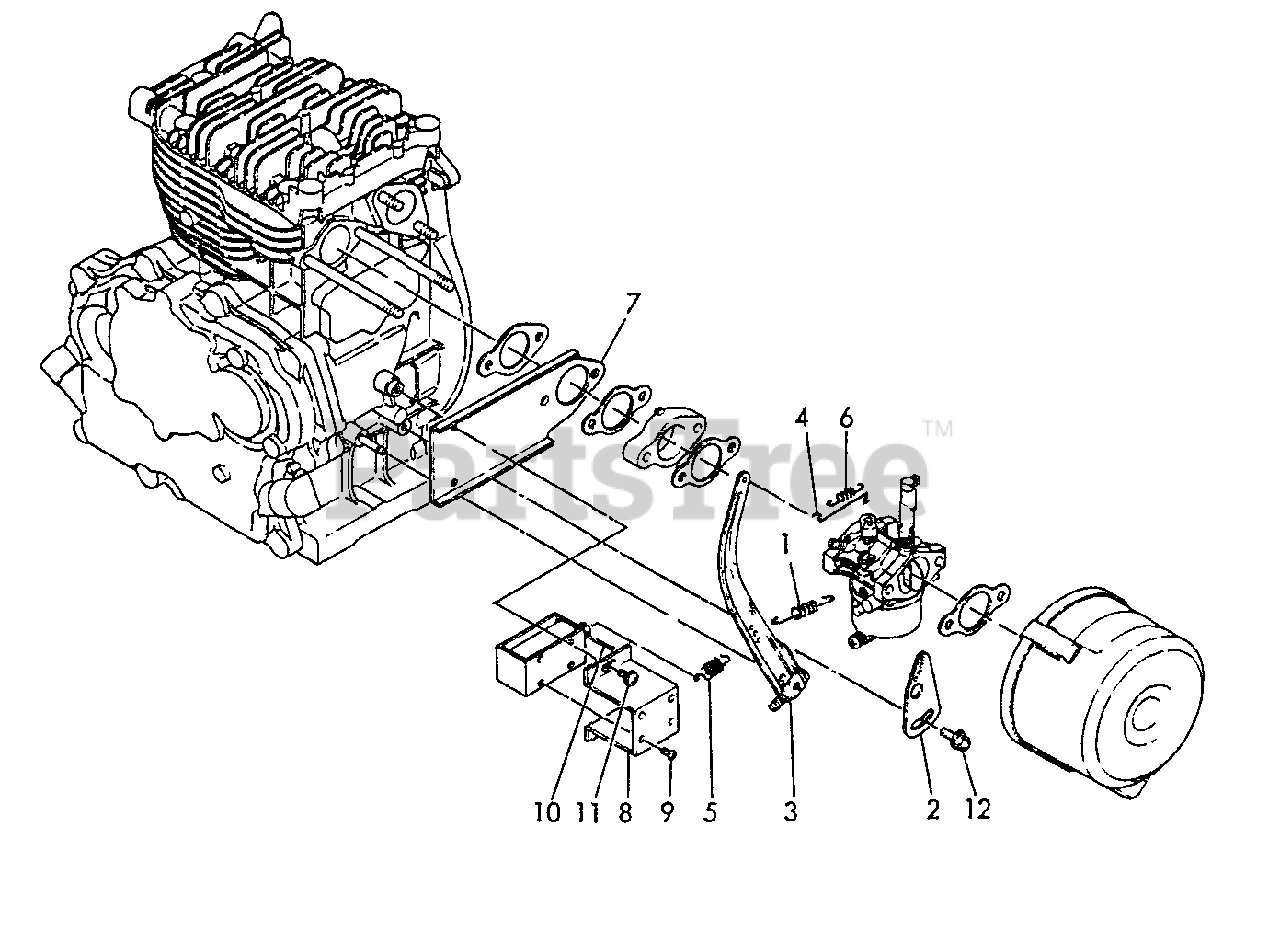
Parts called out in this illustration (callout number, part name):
1	SPRING, REGULATOR
2	HANDLE, REGULATOR
3	LEVER, GOVERNOR
4	LINK, THROTTLE
5	SPRING
6	SPRING, TENSION
7	MOUNT, SOLENOID
8	HOLDER, SOLENOID
9	SCREW - 3×4
10	PIN - 2.5×20 -- COTTER
11	SCREW - 5×10
12	BOLT - 6×8 -- PLATED
